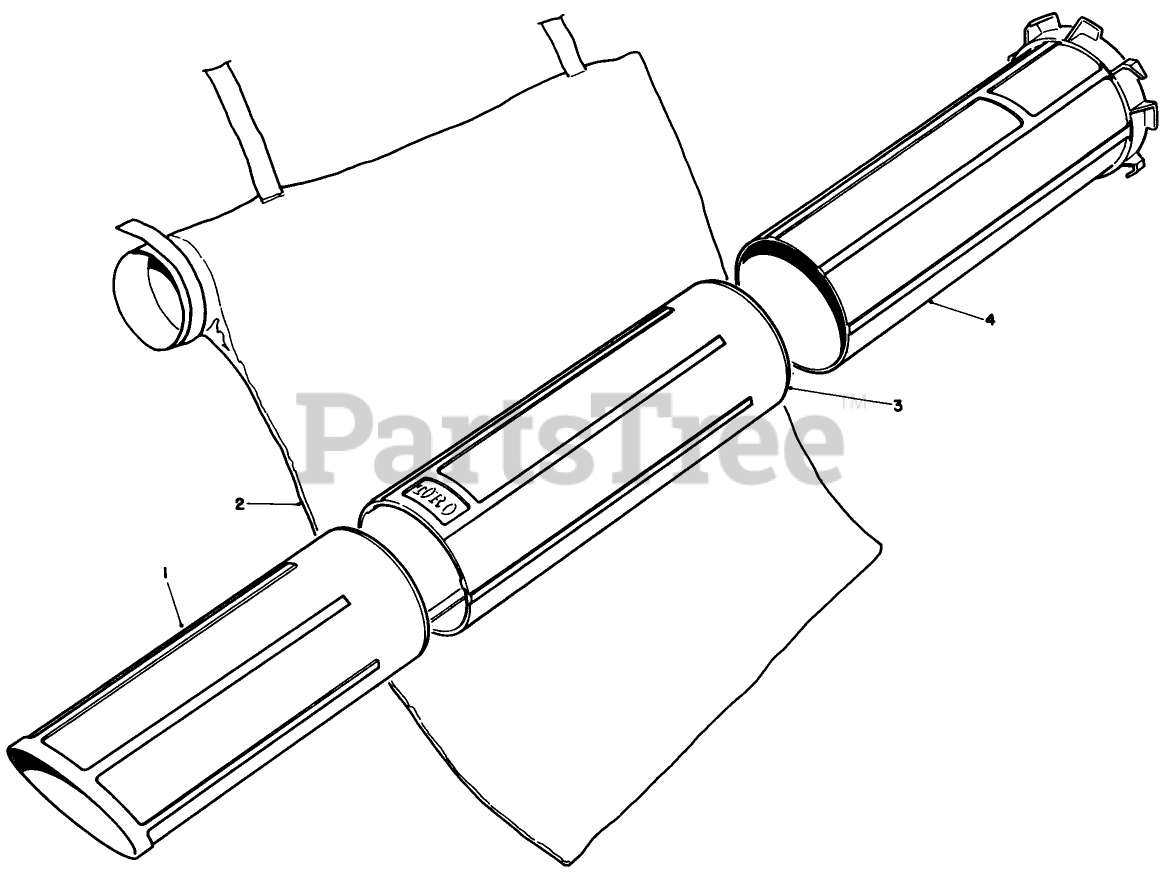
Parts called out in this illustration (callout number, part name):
1	VACUUM BAG
2	Tube-Vacuum, Upper
3	LOWER VAC TUBE
4	MIDDLE VAC TUBE
